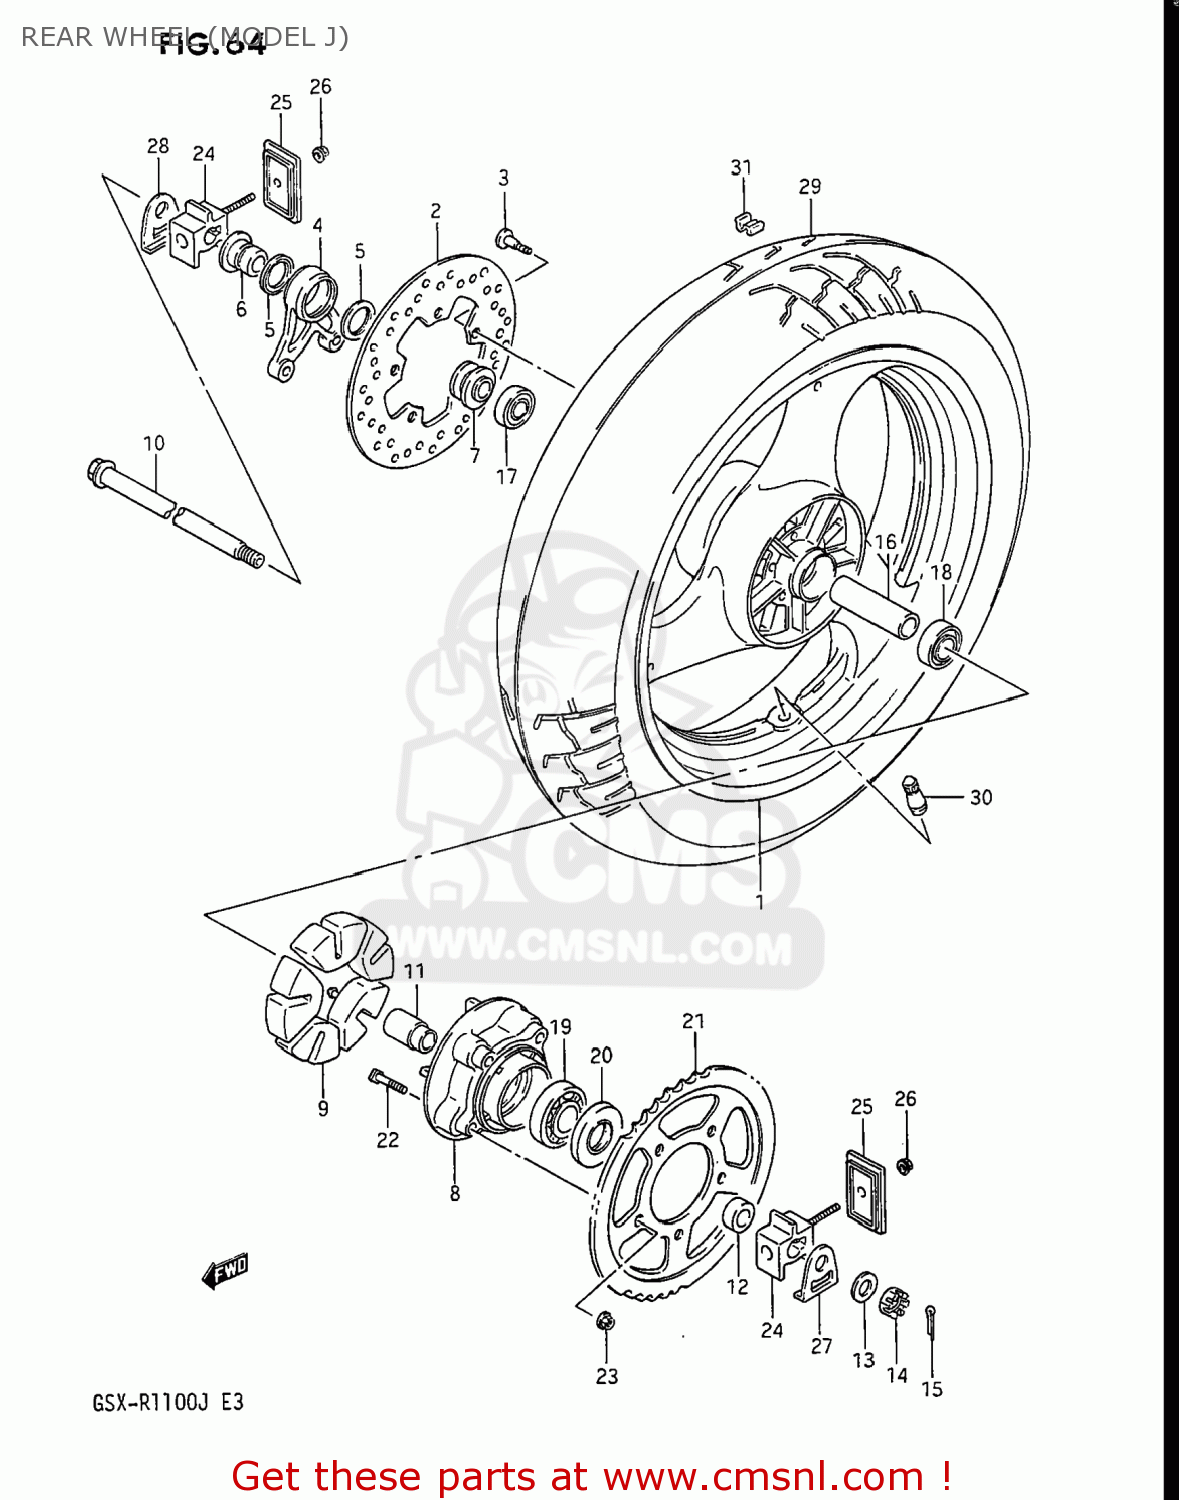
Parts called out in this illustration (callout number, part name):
1	WHEEL,REAR (18XMT4.50)
2	DISC,RR BRAKE
3	BOLT
4	BRACKET,RR CALIPER
5	SEAL,OIL(28X35X5)
6	SPACER,RR CALIPER BRACKET
7	SPACER,RR AXLE,R
8	DRUM,REAR SPROCKET MOUNT
9	ABSORBER,RR HUB SHOCK
10	AXLE,REAR
11	RETAINER,RR HUB BEARING
12	SPACER,RR AXLE,L
13	WASHER
14	NUT
15	PIN, COTTER
16	SPACER(20.8X27.2X97)
17	BEARING
18	BEARING(20X47X14)
19	BEARING(25X62X17)
20	SEAL,OIL(35X62X8)
21	SPROCKET,REAR
22	BOLT(10X44)
23	NUT
24	ADJUSTER,CHAIN
25	PLATE,CHAIN ADJUSTER GUIDE
26	NUT
27	WASHER,CHAIN ADJUSTER
28	WASHER,CHAIN ADJUSTER
29	TIRE COMP,TUBELESS 160
30	VALVE,TIRE
31	BALANCER,WHEEL
